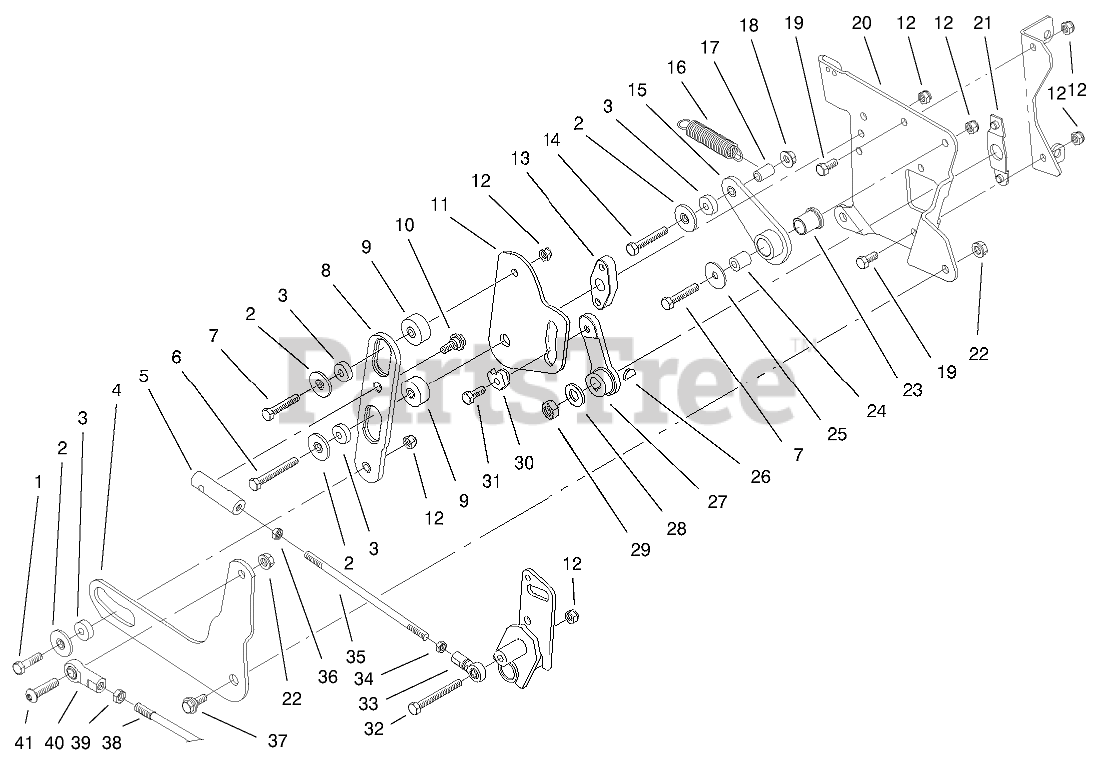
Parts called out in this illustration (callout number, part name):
1	SCREW-HH
2	RETAINER-BEARING
3	BEARING-BALL
4	SLIDER-LIFT
5	END-ROD, RH
6	SCREW-HH
7	SCREW-HH
8	SLIDER-CONTROL, SPEED
9	STANDOFF-CAM PLATE
10	BOLT-SHOULDER
11	PLATE-CAM
12	NUT-LOCK, NI
13	STANDOFF-SLIDER
14	SCREW-HH
15	ARM-RETURN TO NEUTRAL
16	SPRING-IDLER
17	STANDOFF-SPRING
18	WASHER-PLAIN
19	SCREW-HH
20	PLATE-CONTROL
21	LOCATOR-CONTROL PLATE
23	BUSHING-FLANGED
24	SPACER
25	WASHER-FLAT
26	KEY-WOODRUFF
27	ARM-CONTROL, SPEED
28	WASHER-FLAT
29	NUT-LOCK, NI
31	SCREW-THREAD LOCKING
32	SCREW-HH
33	END-ROD, RH
34	NUT-JAM
35	ROD-SLIDER TO PIVOT
36	NUT-JAM
37	BOLT-SHOULDER
38	ROD-LIFT
39	NUT-HJ
40	END-ROD, FEMALE
41	SCREW-HSBH
